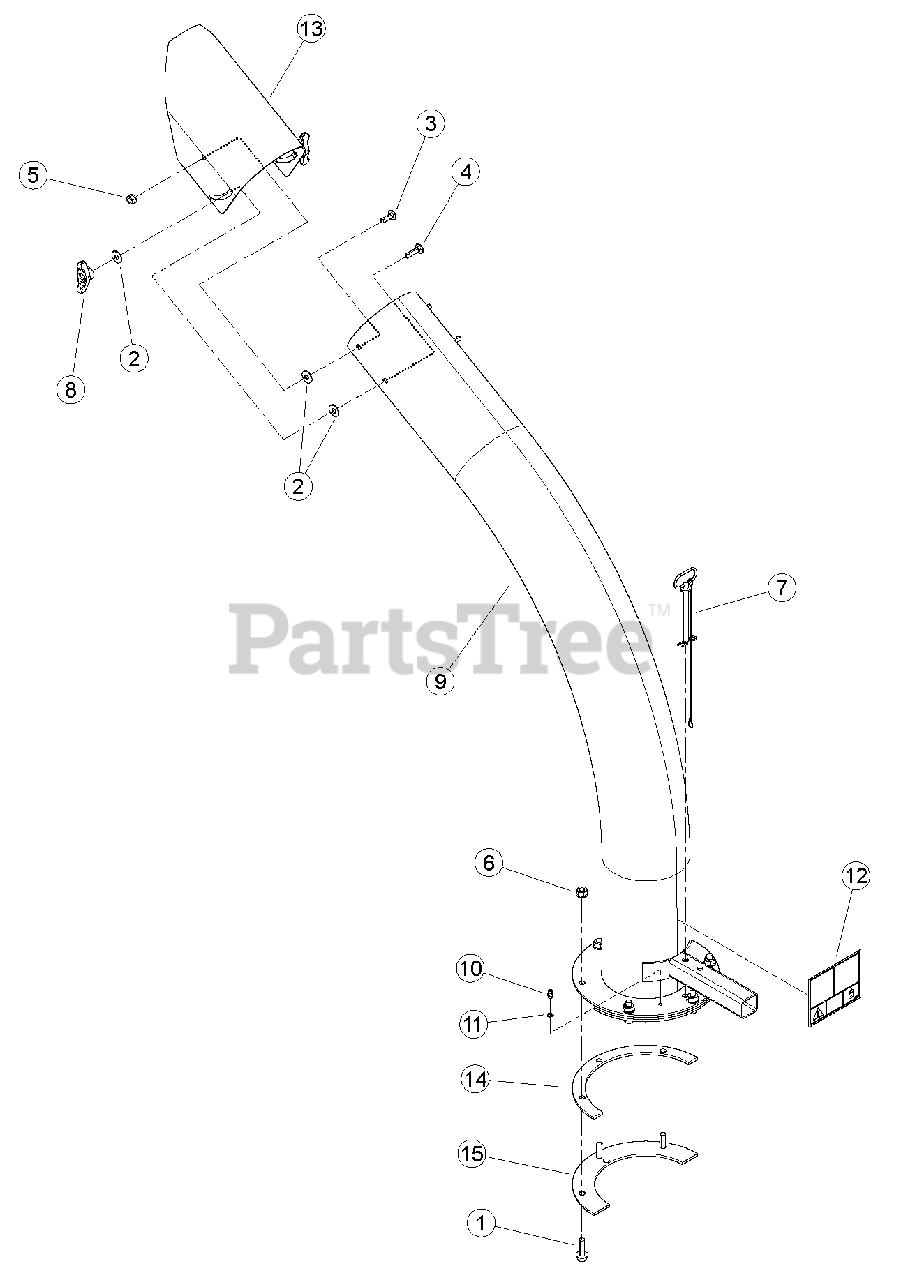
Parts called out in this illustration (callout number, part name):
1	BOLT, 3/8 X 1-1/4 FLANGE NC
2	WASHER, 5/16" FLAT ZP
3	BOLT, 5/16 X 1" GR5 CRG ZP
4	BOLT, 5/16 X 1-1/4" GR5 ZP CRG
5	NUT, 5/16-18 NYLOCK-FLANGE
6	NUT, 3/8-16 NYLOCK FLANGE
7	PIN, 3/8 X 4.25" DISCHARGE
8	KNOB, 5/16-18 UNC TEE W/ LOCKING INSERT
9	ASSEMBLY, 6 INCH DISCHARGE CHUTE, SERVICE PART
10	FITTING, 1/4 SELF-TAP GREASE
11	WASHER, FLAT .254 X .400 X .048
12	DECAL, DISCHARGE DEBRIS & LOCK
13	DEFLECTOR, BLOWER VAC DISCHARGE
14	SPACER, DISCHARGE PIVOT
15	RING, DISCHARGE CLAMP
